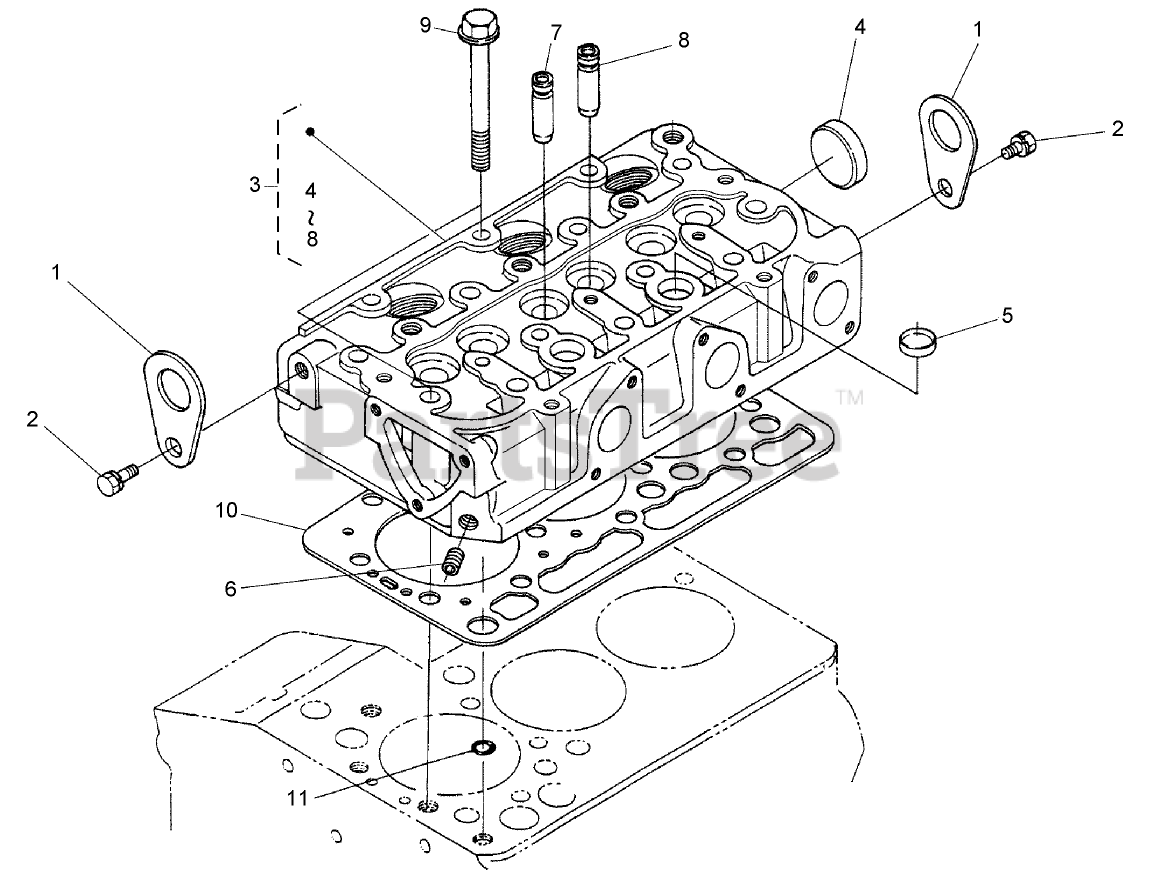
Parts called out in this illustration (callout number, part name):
1	HOOK-ENGINE
3	CYLINDER HEAD ASM
4	CAP-SEALING
5	CAP-SEALING
6	PLUG
7	GUIDE-VALVE, INLET
8	GUIDE-VALVE, EXHAUST
9	BOLT-HEAD, CYLINDER
10	GASKET-HEAD, CYLINDER
11	O-RING
